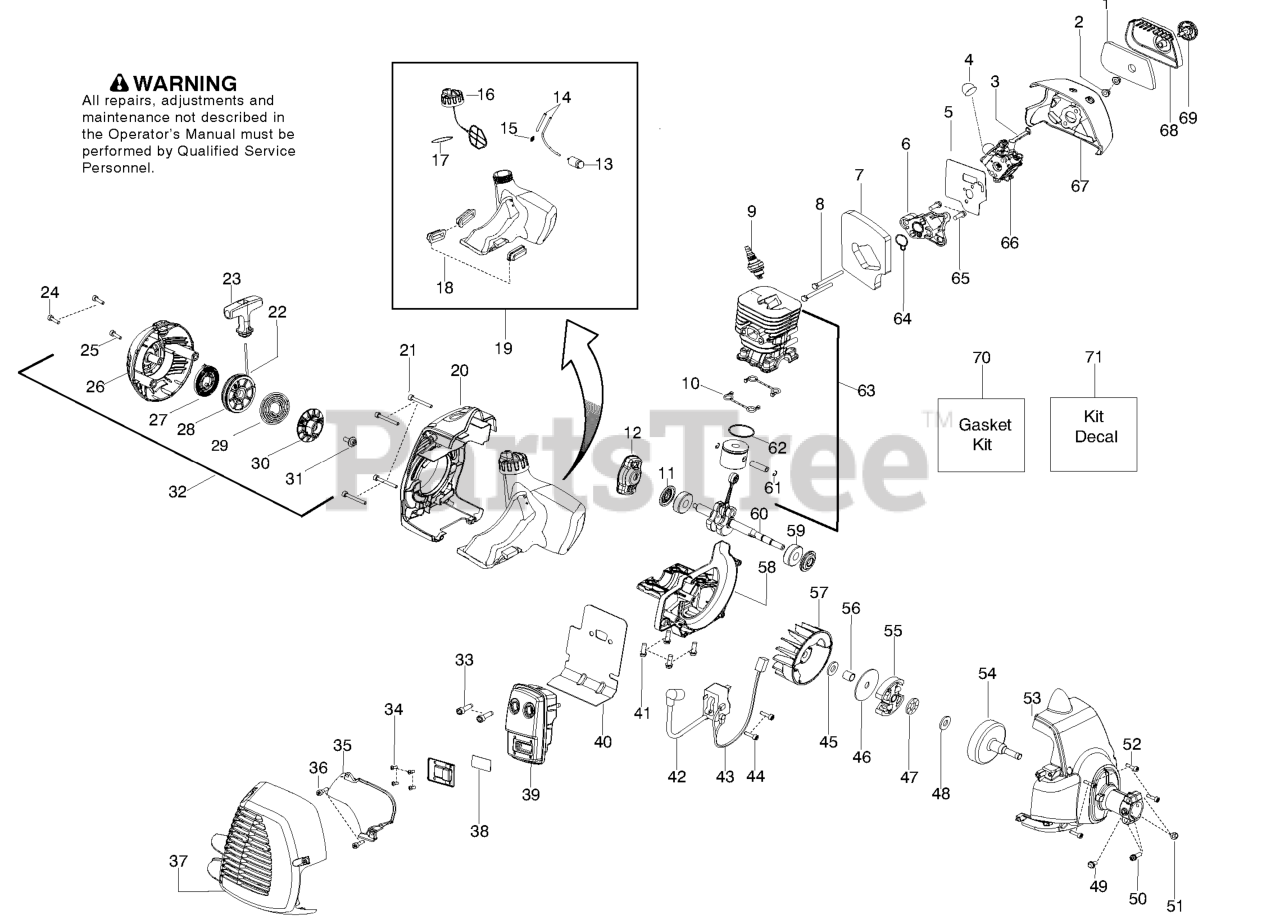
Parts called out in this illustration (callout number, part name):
1	FILTER AIRBOX
3	CHOKE LEVER
4	PURGE BULB ZAMA
5	KIT GASKET CARB 28CC
6	CARB ADAPTOR
7	KIT GASKET 28CC
8	BOLT CARB ADAPTOR
9	Plug - Spark (RCJ-8Y)
10	KIT GASKET 28CC
11	KIT GASKET 28CC
12	STARTER PAWL BRIDGE
13	FUEL PICK-UP ASSY
14	KIT-LINE(FUEL)
15	FUEL LINE FITTING
16	ASSY-CAP W/RETAINER
17	KIT GASKET 28CC
18	ISOLATOR FUEL TANK
19	KIT FUEL TANK HVA
20	KIT STARTER HSG HVA 128
22	KIT ROPE
23	HANDLE - STARTER
24	SCREW M5-0.8X30MM
25	SCREW M4 X 1.75 PT 16MM
26	KIT STARTER HSG HVA 128
27	KIT STARTER SPRING
28	KIT STARTER PULLEY
29	SPRING - DRIVER
30	DRIVER PULLEY
32	ASSY STARTER HSG HVA
33	BOLT MUFFLER
34	SCREW-6-19X5/16PLAST PA
35	SHIELD HEAT
36	SCREW M4 X 1.75 PT 16MM
37	KIT MUFFLER GUARD HVA
38	KIT SPARK ARRESTOR SCREEN
39	KIT MUFFLER LE28
40	KIT GASKET 28CC
41	SCREW-M5-0.8 X 25MM(TAP)
42	IGNITION MODULE MBU-7
43	ASSY MODULE LEAD WIRE
44	SCREW M4 X .70 TT 16MM
45	WASHER CLUTCH
46	WASHER-CLUTCH
47	BEARING THRUST
48	WASHER THRUST
49	Screw
50	Screw
51	LOCKNUT-HEX 10-24
52	SCREW M4 X .70 TT 16MM
53	Assy - Fan Housing
54	ASSY-CLUTCH DRUM
55	ASSEMBLY CLUTCH
56	SPACER FLYWHEEL
58	CRANKCASE CAST LE28
59	BEARING RADIAL BALL (6201)
60	ASSY CRANKSHAFT
61	WRIST PIN RET.
62	RING PISTON
63	KIT PISTON & CYLINDER
64	KIT GASKET 28CC
65	SCREW-M5-0.8 X 25MM(TAP)
66	KIT CARB
67	RP_AIR BOX
68	COVER-AIR BOX
69	KNOB ASSY AIRBOX COVER
70	KIT GASKET 28CC
71	KIT DECAL WARNING
